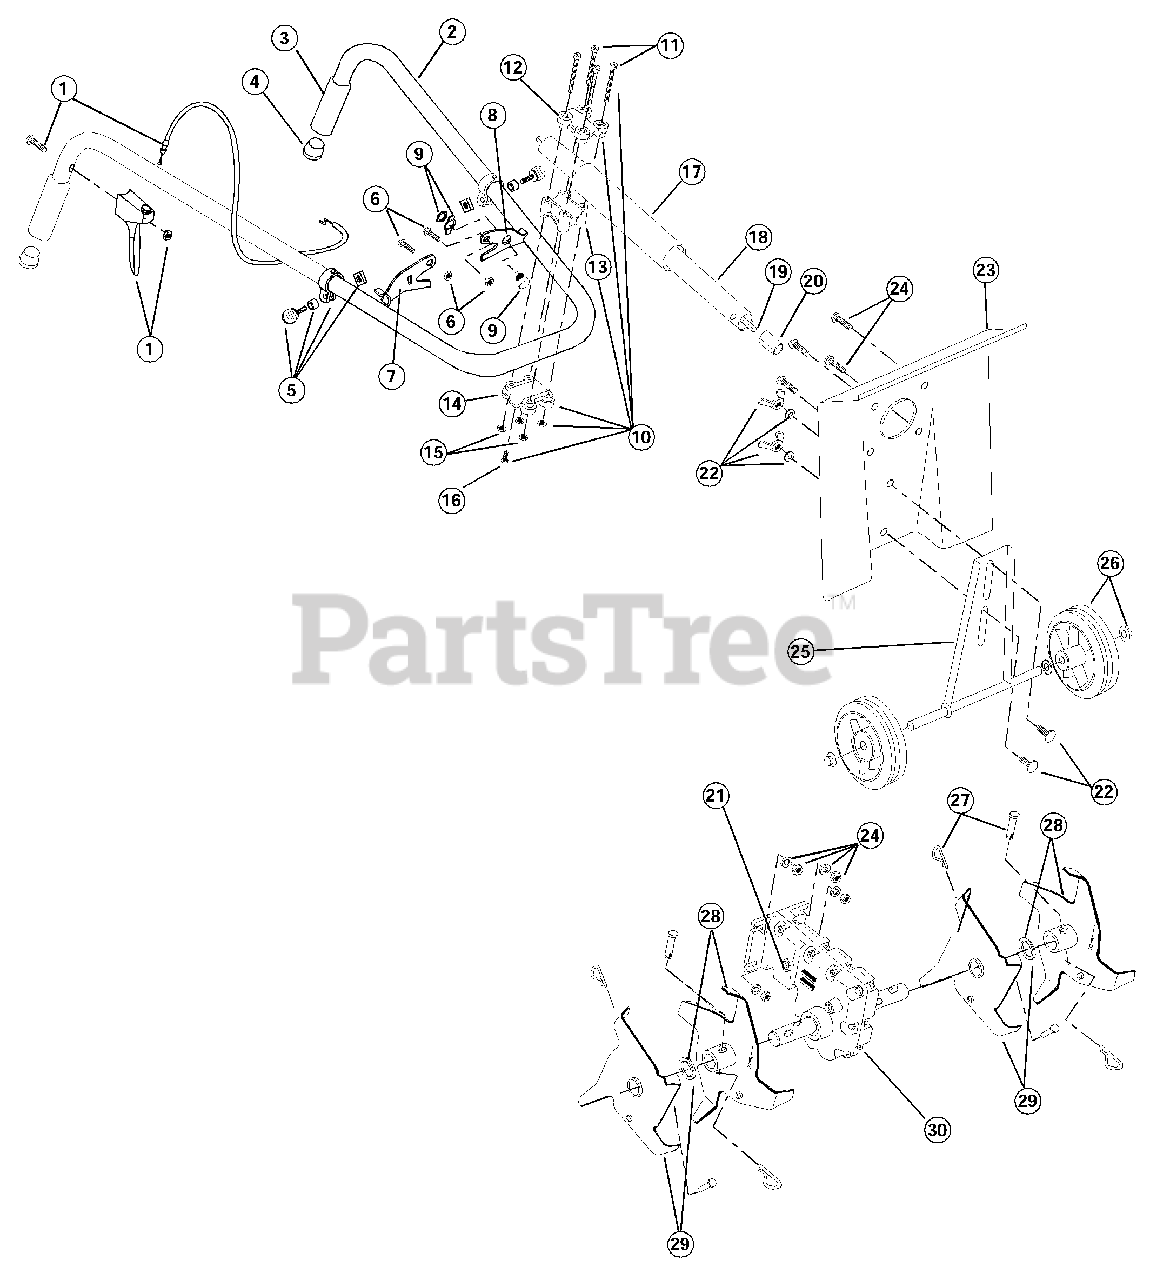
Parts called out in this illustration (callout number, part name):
1	Throttle Trigger and Cable Assembly
2	Handle Bar w/Clamp Assemblies
4	Tube Closure
5	Clamp Assembly
6	Engine Bracket Mounting Hardware
7	Engine Mount Bracket, R.H.
8	Engine Mount Bracket, L.H.
9	Switch Assembly
10	Handle Bracket Assembly
12	Upper Handle Clamp
13	Middle Handle Clamp
14	Lower Handle Clamp
16	Anti-Rotation Screw
18	Drive Shaft Housing Assembly
19	Flexible Drive Shaft
20	Retainer Sleeve
21	Sleeve Retainer Bolt
22	Wheel Bracket Mounting Hardware
24	Guard Mounting Hardware
25	Wheel Bracket Assembly
26	Wheel Assembly
27	Tine Fastener Assembly
28	Tine Assembly (Left Outer or Right Inner)
29	Tine Assembly (Left Inner or Right Outer)
30	Gear Box Assembly
